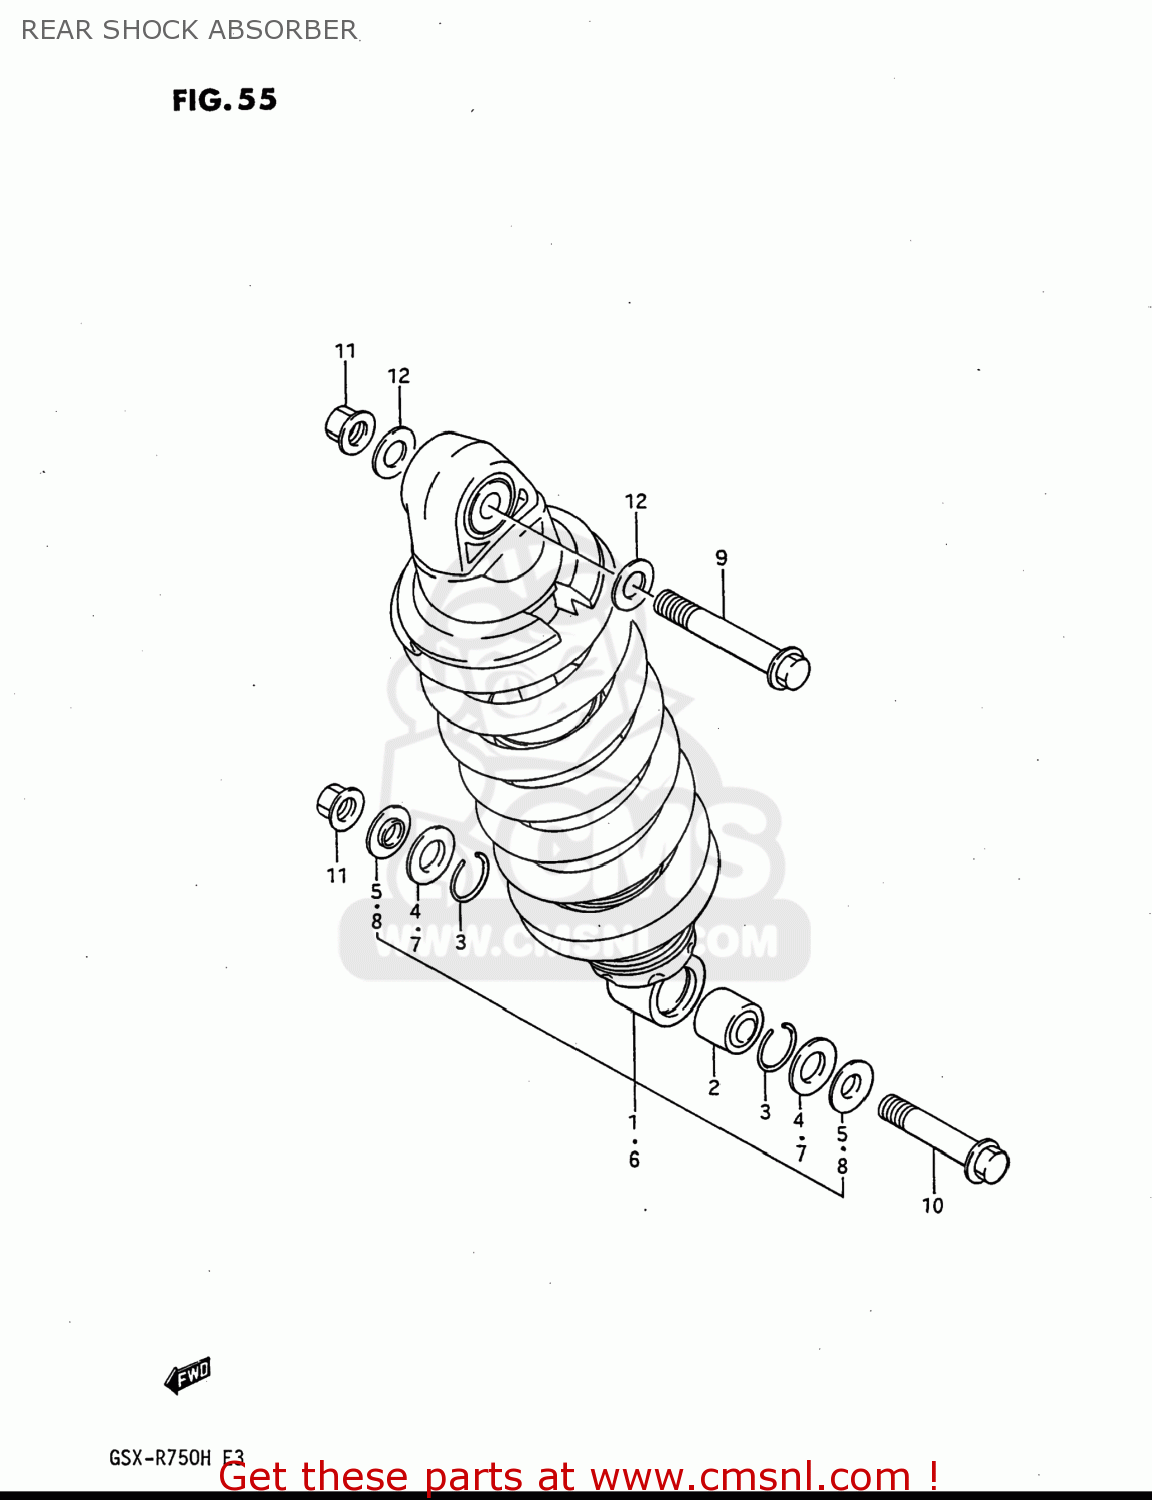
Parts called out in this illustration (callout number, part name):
1	ABSORBER ASSEMBLY,REAR SHOCK
2	BEARING,REAR SHOCK ABSORBER
3	RING
4	SEAL,DUST UPR
5	COLLAR,UPR
6	ABSORBER ASSY,RR SHOCK
7	SEAL DUST
8	COLLAR
9	BOLT
10	BOLT,RR CUSHION ROD UPR
11	NUT
12	WASHER,REAR SHOCK ABSORBER
